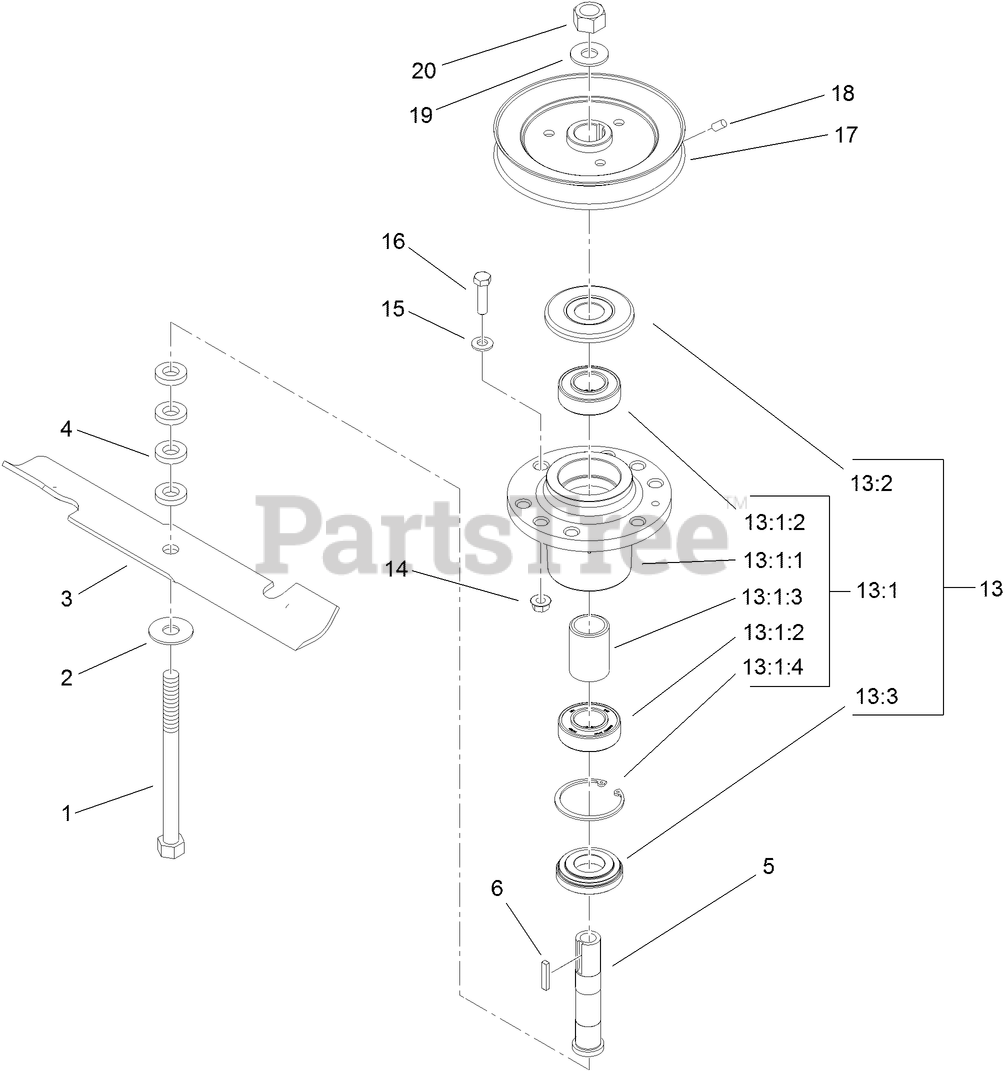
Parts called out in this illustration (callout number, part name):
1	SCREW-CAP, HH
2	WASHER-SPRING
3	BLADE-NOTCHED
4	SPACER
5	TUBE-SPINDLE, SHORT
13	CUTTER HOUSING ASM
13:1	CUTTER HOUSING ASM
13:1:1	HOUSING-SPINDLE
13:1:2	BEARING-JACKSHAFT
13:1:3	Spacer-Bearing
13:1:4	RING-SNAP
13:2	Guard-Bearing, Top
13:3	SPACER-GUARD, BOTTOM
14	NUT-HF
15	WASHER-SPRING
16	SCREW-HH
17	SHEAVE
18	SCREW-SET
19	WASHER-RETAINER, SHEAVE
20	NUT-HEX
